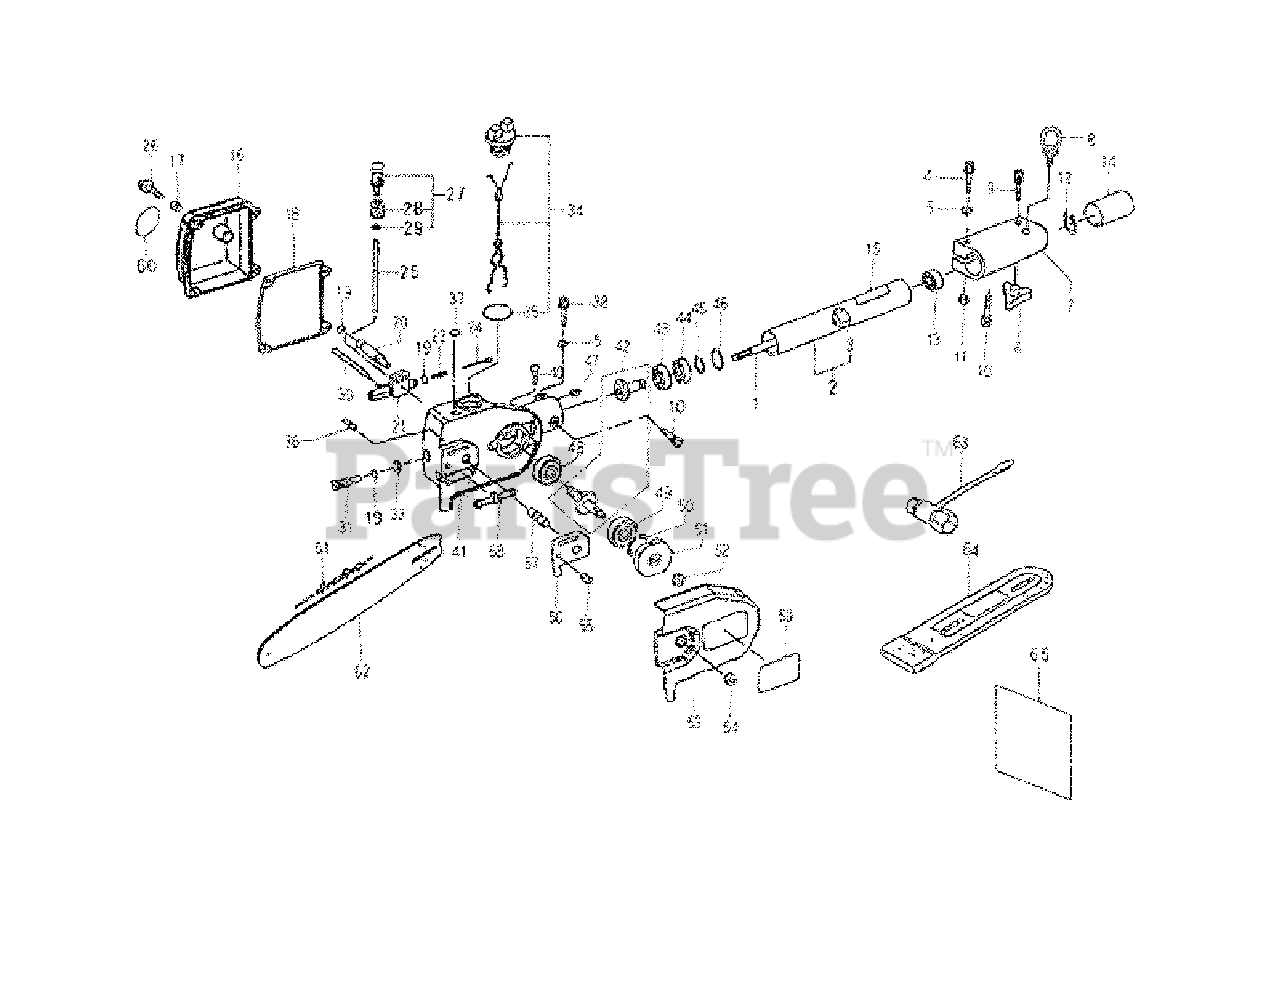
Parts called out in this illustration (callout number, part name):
1	Shaft, Drive
2	Pipe complete
5	Spring Washer
13	Ball Bearing
15	Caution Plate
16	Cover, Oil Tank
21	Pump, Lubricating Oil
24	Piston, Oil Pump
27	Filter Assembly Oil
28	Filter, Oil
31	Adjuster, Oil Pump
34	Cap, Oil Fill
42	Gear Assembly
43	Ball Bearing
44	Ball Bearing
48	Ball Bearing
49	Ball Bearing
56	Plate, Guide
60	Caution Plate
61	Chain; 9.52 mm (3/8")
62	Bar, Chain 250mm (10")
64	Cover, Chain
